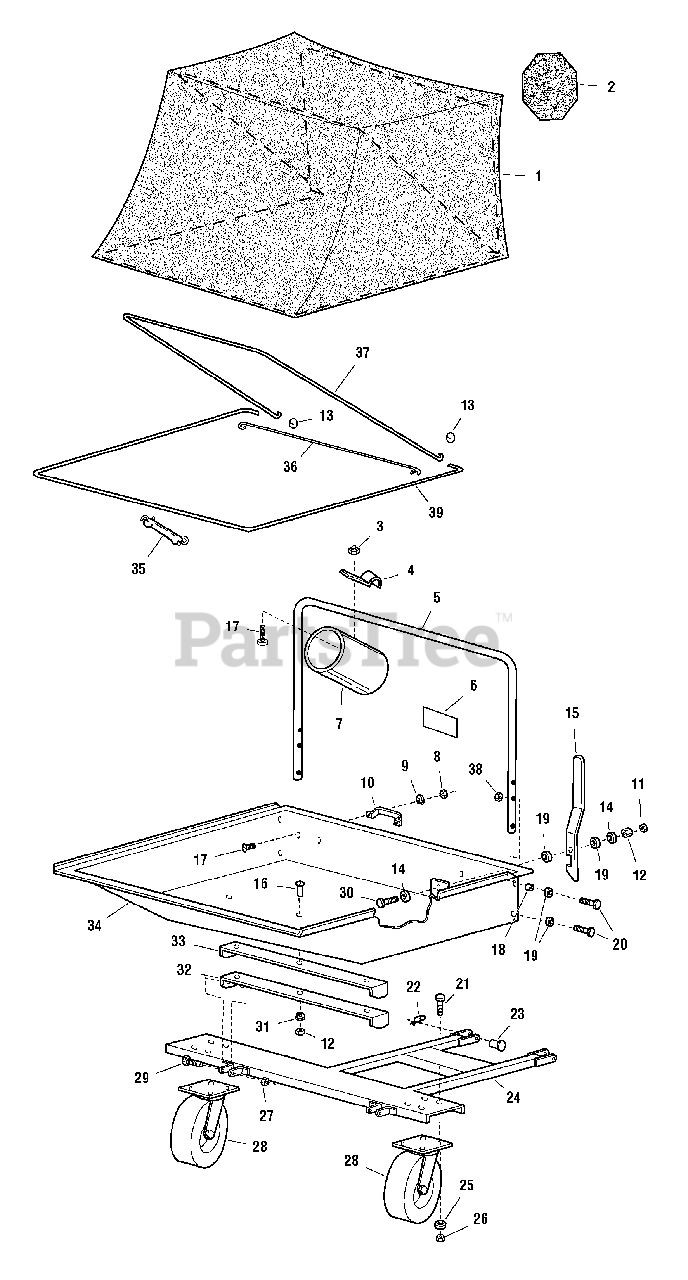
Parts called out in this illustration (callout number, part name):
2	PATCH, With Velcro
3	NUT, Hex, 1/4-20
4	SLEEVE CLAMP
5	TUBE, Support
6	DECAL, Max Capacity
7	SLEEVE, Connecting
8	NUT, Hex, 1/4-20
9	LOCKWASHER, 1/4
10	LIFT HANDLE
11	NUT, Hex, Jam, 5/16-18
12	NUT, Hex, 5/16-18
13	COTTER CIRCLE
14	WASHER, Compression
15	HANDLE, Latch
16	SCREW, Slotted, 5/16-18 x 3/4
17	CAPSCREW, Hex Head, 1/4-20 x 1/2
18	SPACER, Plastic
19	WASHER, 5/16
20	CAPSCREW, Hex Head, 5/16-18 x 1-1/2
21	CAPSCREW, Hex Head, 3/8-16 x 1
22	PIN, Retainer
23	PIN, Round Head 1/2 x 1-1/2
24	FRAME, Jarco Cart
25	WASHER, 3/8
26	NUT, Hex Centerlock, 3/8-16
27	NUT, Hex Centerlock, 1/2-13
28	WHEEL ASSEMBLY
29	CAPSCREW, Hex Head, 1/2-13 x 1-1/4
30	CAPSCREW, Hex Head, 5/16-18 x 1-1/4
31	LOCKWASHER, 5/16
33	"U" BRACKET
34	BOX, 44" Jrco Cart
35	Rubber Strap
36	ROD, Straight
37	ROD, Support
38	NUT, Hex, Centerlock, 5/16-18
